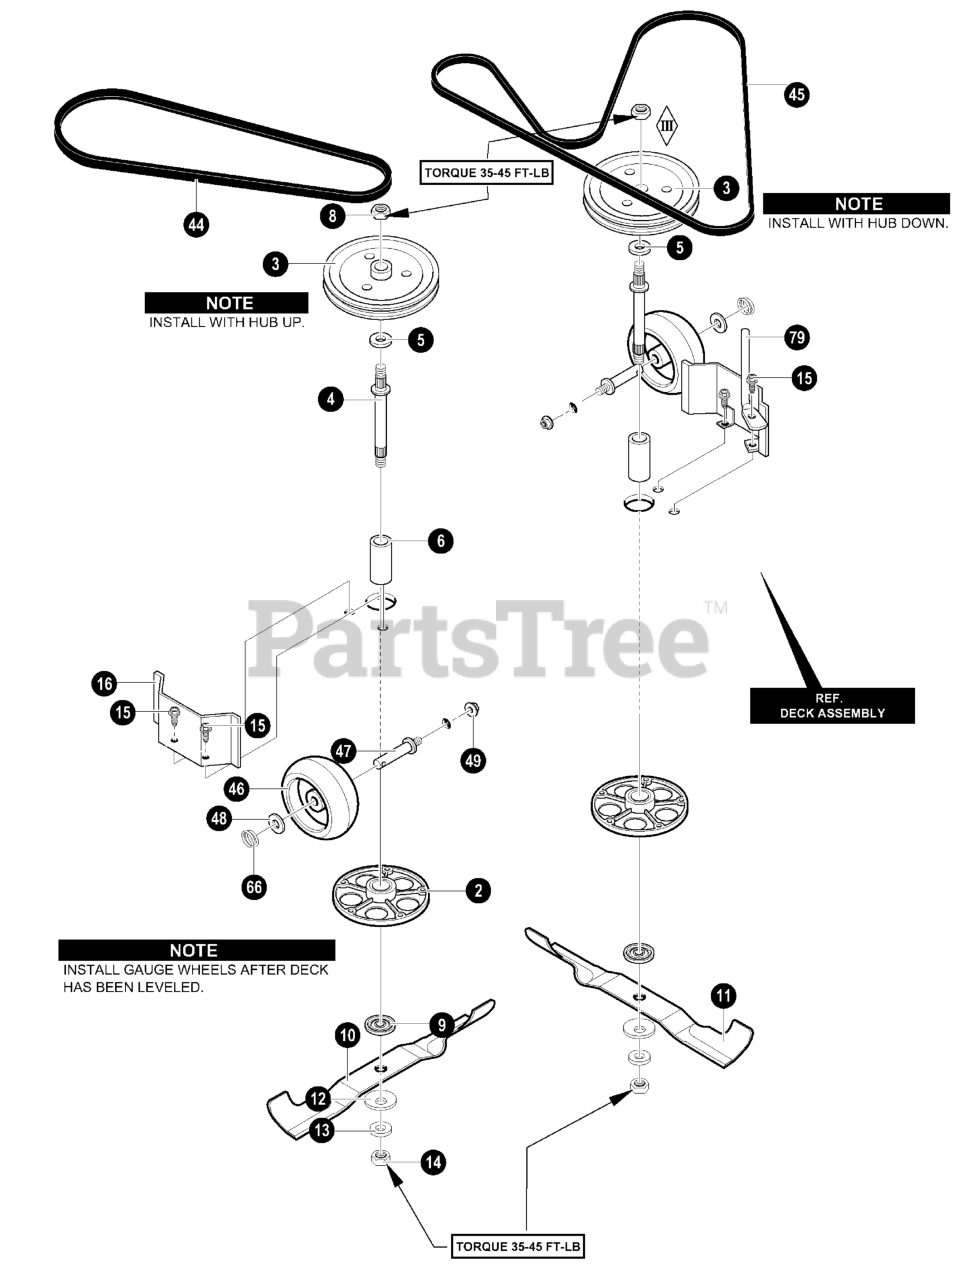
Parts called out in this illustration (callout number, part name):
2	ASSEMBLY, JACKSHAFT HOUSING
3	PULLEY, DECK
4	JACKSHAFT
5	WASHER, FLAT
6	SPACER, .625X.875X1.91
8	NUT, 9/16-18
9	ADAPTER, DECK/BLADE 40"
10	BLADE, LH
11	BLADE, RH
12	WASHER,BELLVILLE
13	WASHER, FLAT
14	NUT, 9/16-18
15	SCREW,3/8-16X1.00
16	COVER PULLEY
44	BELT, V 46.5LG
45	BELT, DECK
46	GAUGE WHEEL
47	BOLT, SHOULDER
48	WASHER, FLAT
49	NUT, 3/8-16
66	PIN, CIRCLE
79	ROD, BELT GUIDE
